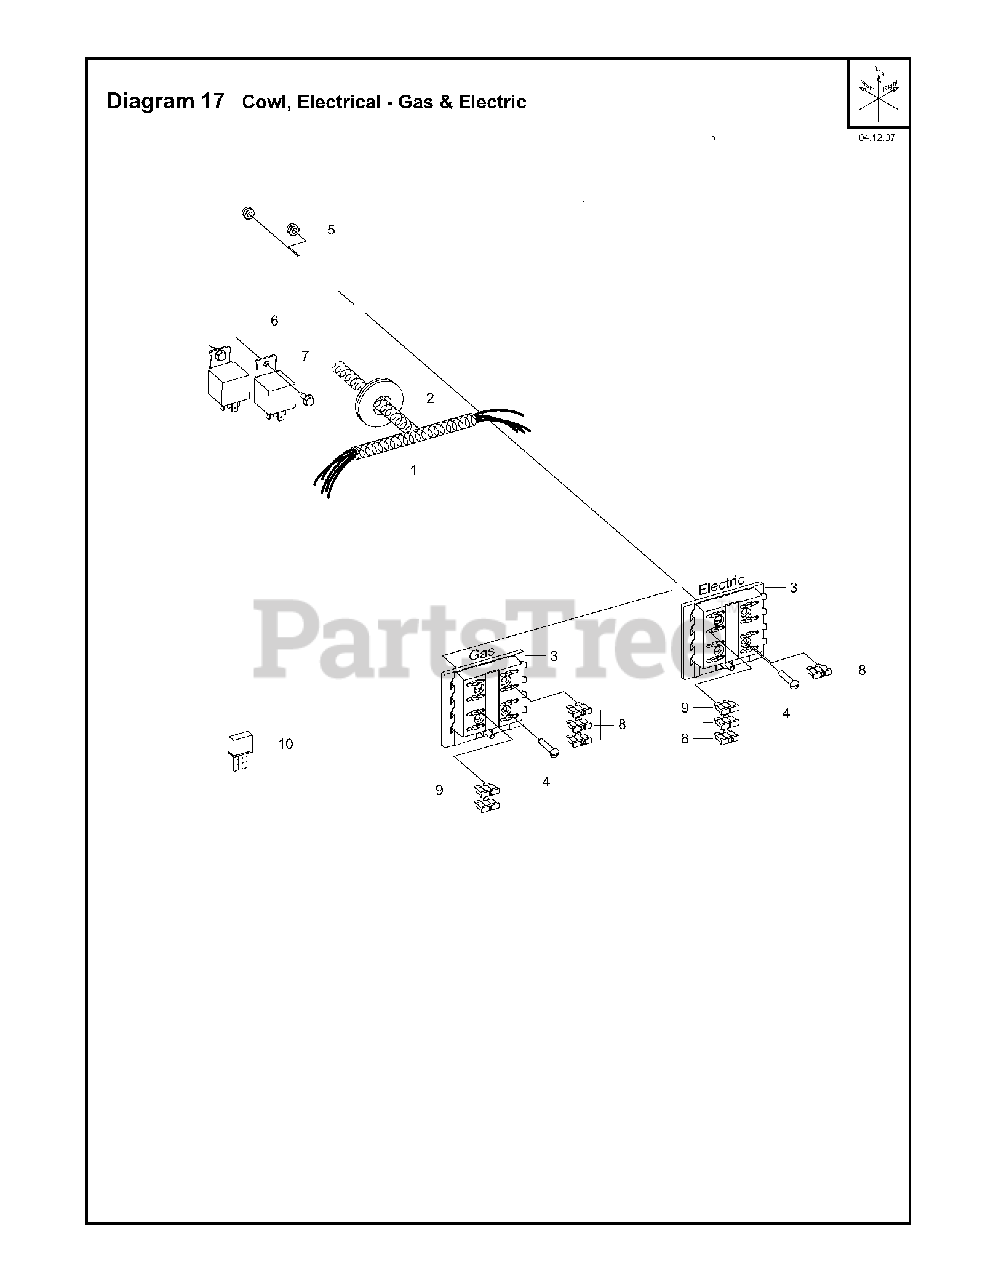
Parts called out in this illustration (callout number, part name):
1	WIRING HARNESS. PRO STD
1	SCHILD CRDH145-36
4	RHMS. 10-24 x 1 Z/P
5	LOCKNUT. FIBER 10-24
6	RELAY
7	HWHSTS #10-24 x .5 TYPE F
10	CIRCUIT BREAKER. 30 AMP
